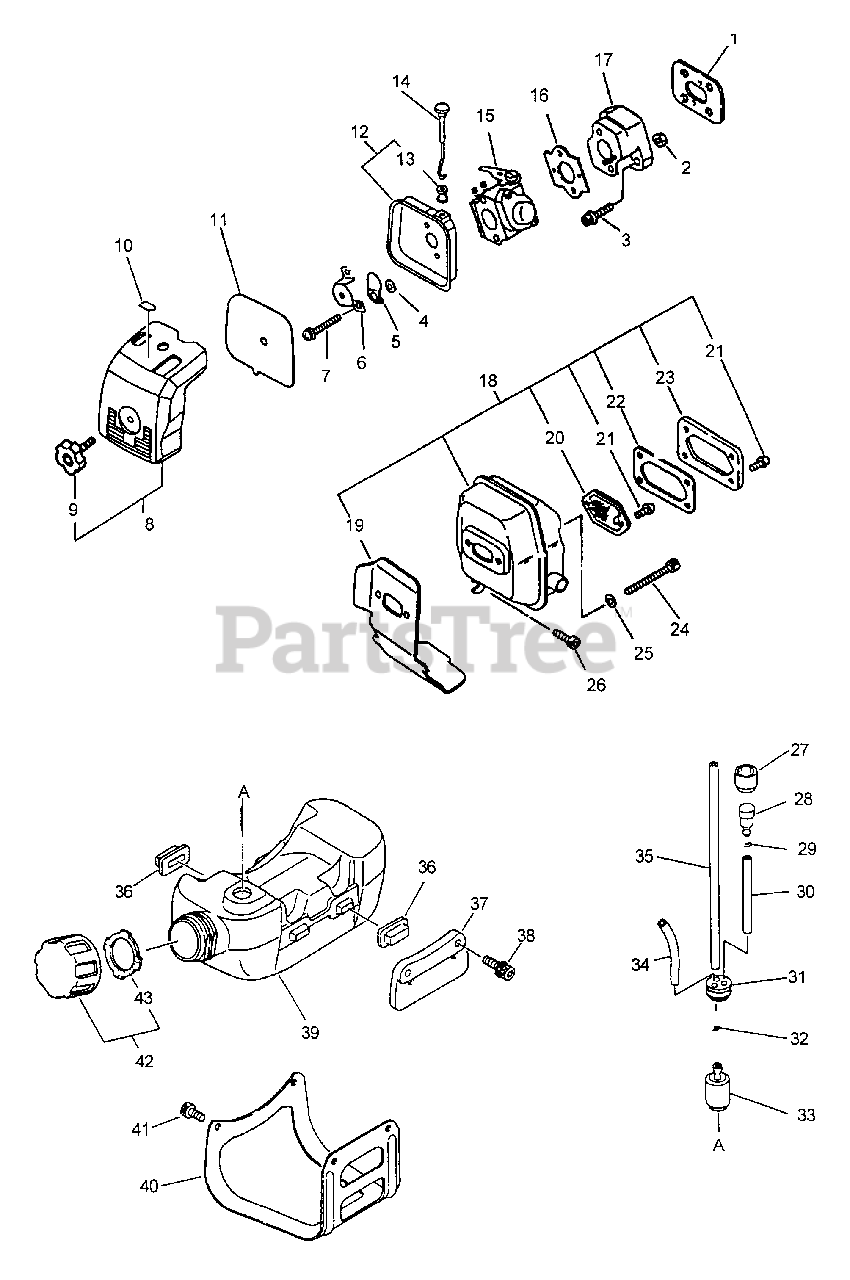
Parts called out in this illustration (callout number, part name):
1	GASKET, INTAKE
3	SCREW - 5X25
4	WASHER - 5
5	SHUTTER, CHOKE
6	PLATE, PREVENT
7	SCREW - 5X57
8	AIR FILTER COVER ASSY
9	THUMBSCREW
10	LABEL - CHOKE
11	FILTER, AIR - HEAVY DUTY
12	CASE, AIR FILTER
14	ROD, CHOKE
15	CARBURETOR WT-418A
16	GASKET, INTAKE
17	INSULATOR, INTAKE
18	MUFFLER ASSY
19	GASKET, EXHAUST
20	SCREEN, SPARK ARRESTOR
21	SCREW - 4X10
22	GASKET, EXHAUST
23	GUIDE, EXHAUST
24	SCREW - 5X60
25	WASHER - 5
26	SCREW - 5X12
27	COVER, VENT
28	VENT, FUEL TANK
29	CLIP - 5.5
30	PIPE - 3X5X50 -- BLACK
31	GROMMET
32	CLIP - 6
33	FILTER, FUEL
34	PIPE - 3X6X90 -- CLEAR
35	PIPE - 3X5X180 -- BLACK
36	CUSHION, FUEL TANK
37	BRACKET, FUEL TANK
38	SCREW - 5X20
39	TANK, FUEL
40	GUARD, FUEL TANK
41	SCREW - 5X12
42	CAP ASSY
43	GASKET, CAP
